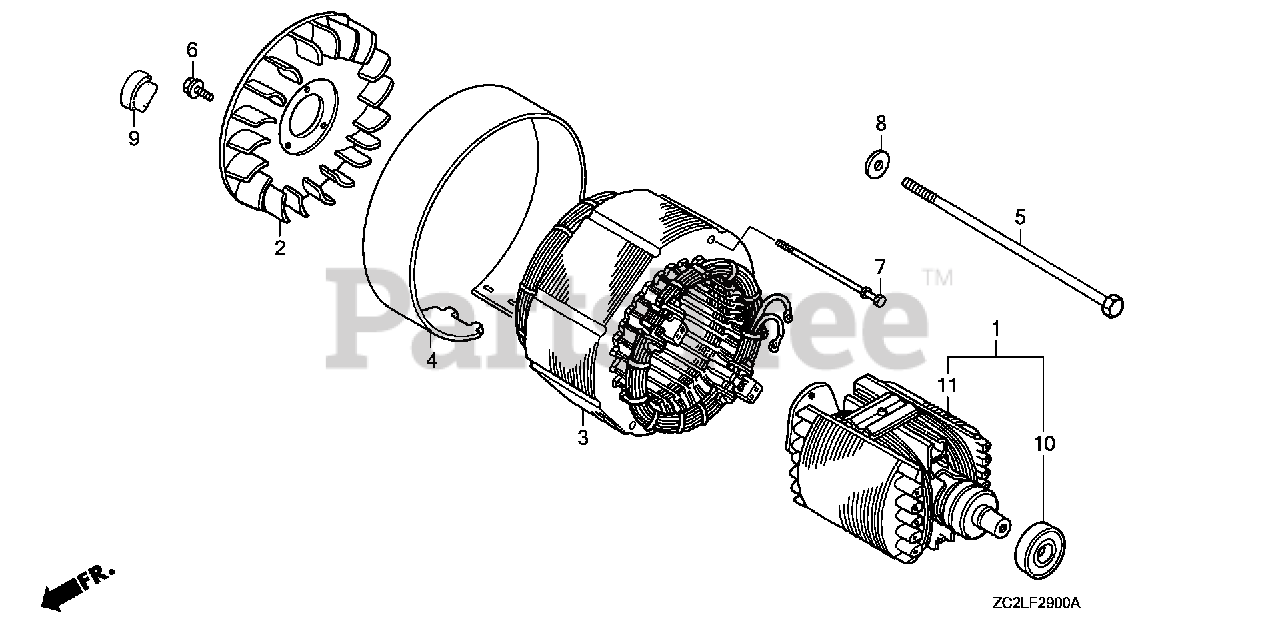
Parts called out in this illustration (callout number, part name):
1	ROTOR
2	FAN, GENERATOR COOLING
3	STATOR ASSY.
4	COVER, STATOR
5	BOLT, HEX. (10X250)
6	SCREW, TAPPING (5X14)
7	BOLT-WASHER (5X195)
8	WASHER (10.5MM)
9	GROMMET, CRANKCASE
10	BEARING ASSY. (6204)
11	ROTOR
